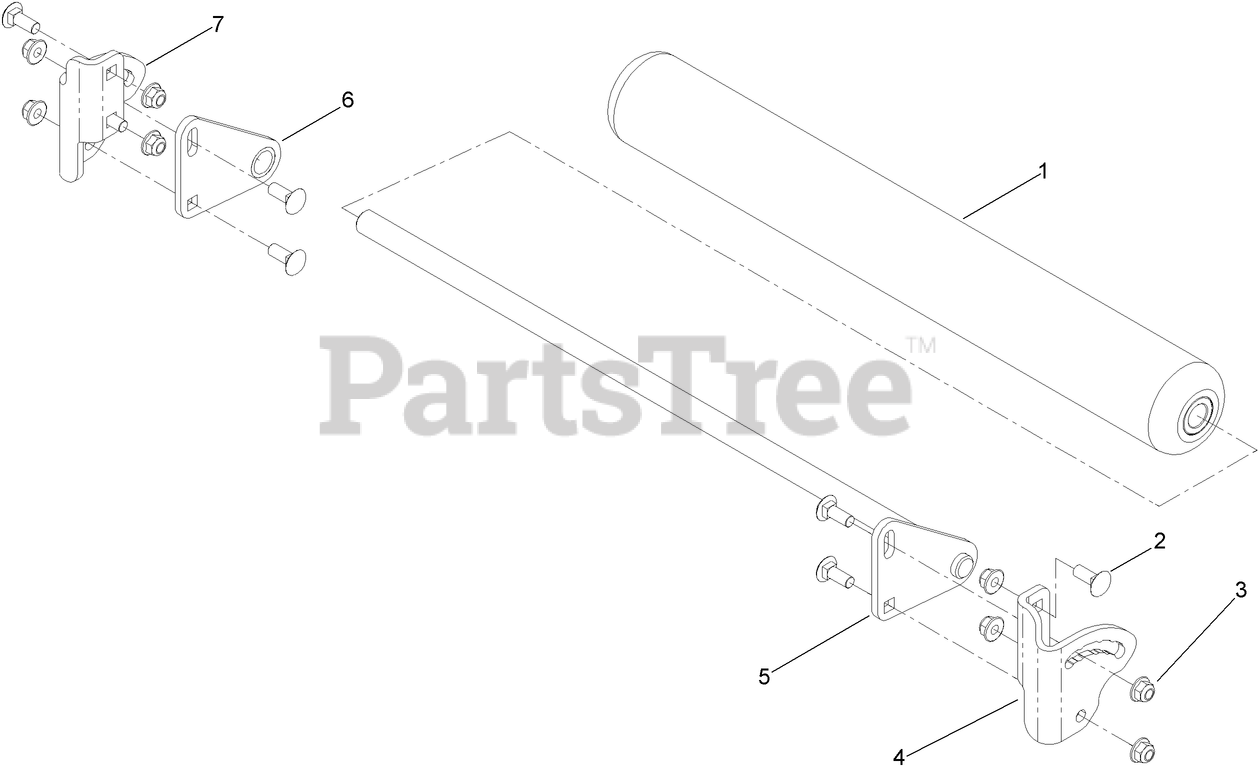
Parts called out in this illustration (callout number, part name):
1	ROLLER-STRIPER
2	BOLT-CARR
3	NUT-HF, NI
4	BRACKET-STRIPER, LH
5	ROLLER-SHAFT
6	STRIPER
7	BRACKET-STRIPER, RH
